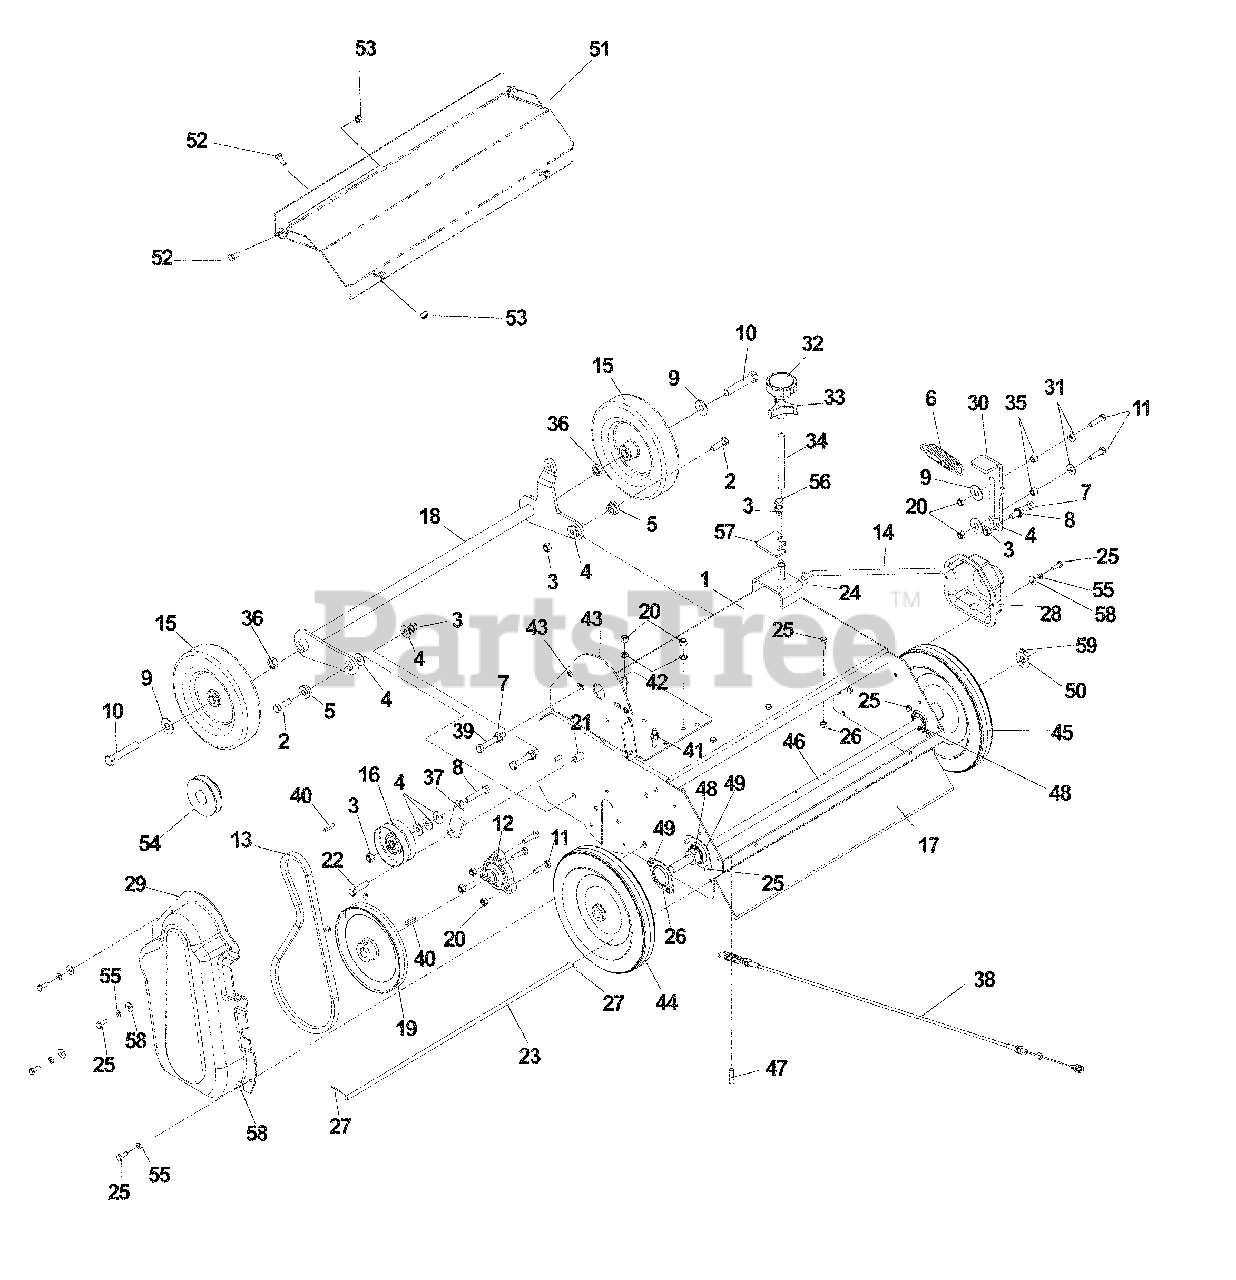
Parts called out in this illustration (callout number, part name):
1	BODY
2	HCS 3/8C X 1 1/4
3	NUT, 3/8C, NYLOC
4	WASHER, 3/8, FLAT
8	HCS 3/8C X 2
9	WASHER, 1/2, FLAT
10	HCS 1/2C X 2 3/4
11	HCS 5/16C X 1 1/4
12	C.I. FLANGE BEARING
15	WHEEL, 8 X 1 3/4
16	IDLER PULLEY, FLAT
18	FRONT AXLE
19	PULLEY W/SET SCREW
20	NUT, 5/16, NYLOC
22	HCS 3/8C X 1 1/2
24	COTTER PIN
25	HCS 1/4C X 3/4
26	NUT, 1/4C, NYLOC
27	COTTER PIN
28	SHAFT GUARD
29	BELT GUARD
31	WASHER, 5/16, FLAT
32	KNOB
33	KNOB
34	ROD, THREADED
35	SPACER, PULLEY
36	NUT, 1/2 HEX, JAM
37	IDLER ARM, ORANGE
39	HCS 3/8C X 2 1/2
40	KEY, 3/16 X 3/16 X 1
41	HCS 5/16C X 1 3/4
42	LOCKWASHER, 5/16
43	BACKING PLATE
44	WHEEL, 10 X 1 3/4, DRILLED
45	WHEEL, 10 X 1 3/4, W/BUSHINGS
46	AXLE, REAR
47	ROLL PIN, 1/4 X 1 1/8
48	BEARING, 5/8" W/COLLAR
49	FLANGE, FOR BEARING 5/8"
50	WASHER, 5/8, SAE
51	REAR COVER
52	HCS 1/4C X 5/8
53	NUT, 1/4C, NYLOC
54	PULLEY, ENGINE W/SET SCREW
55	LOCKWASHER, 1/4
56	SCREW, 3/8C X 1
57	DEPTH SHIM
58	WASHER, 1/4, FLAT
59	COTTER PIN, 1/8 X 1 ½
60	KNURLED INSERT, 1/4-20
